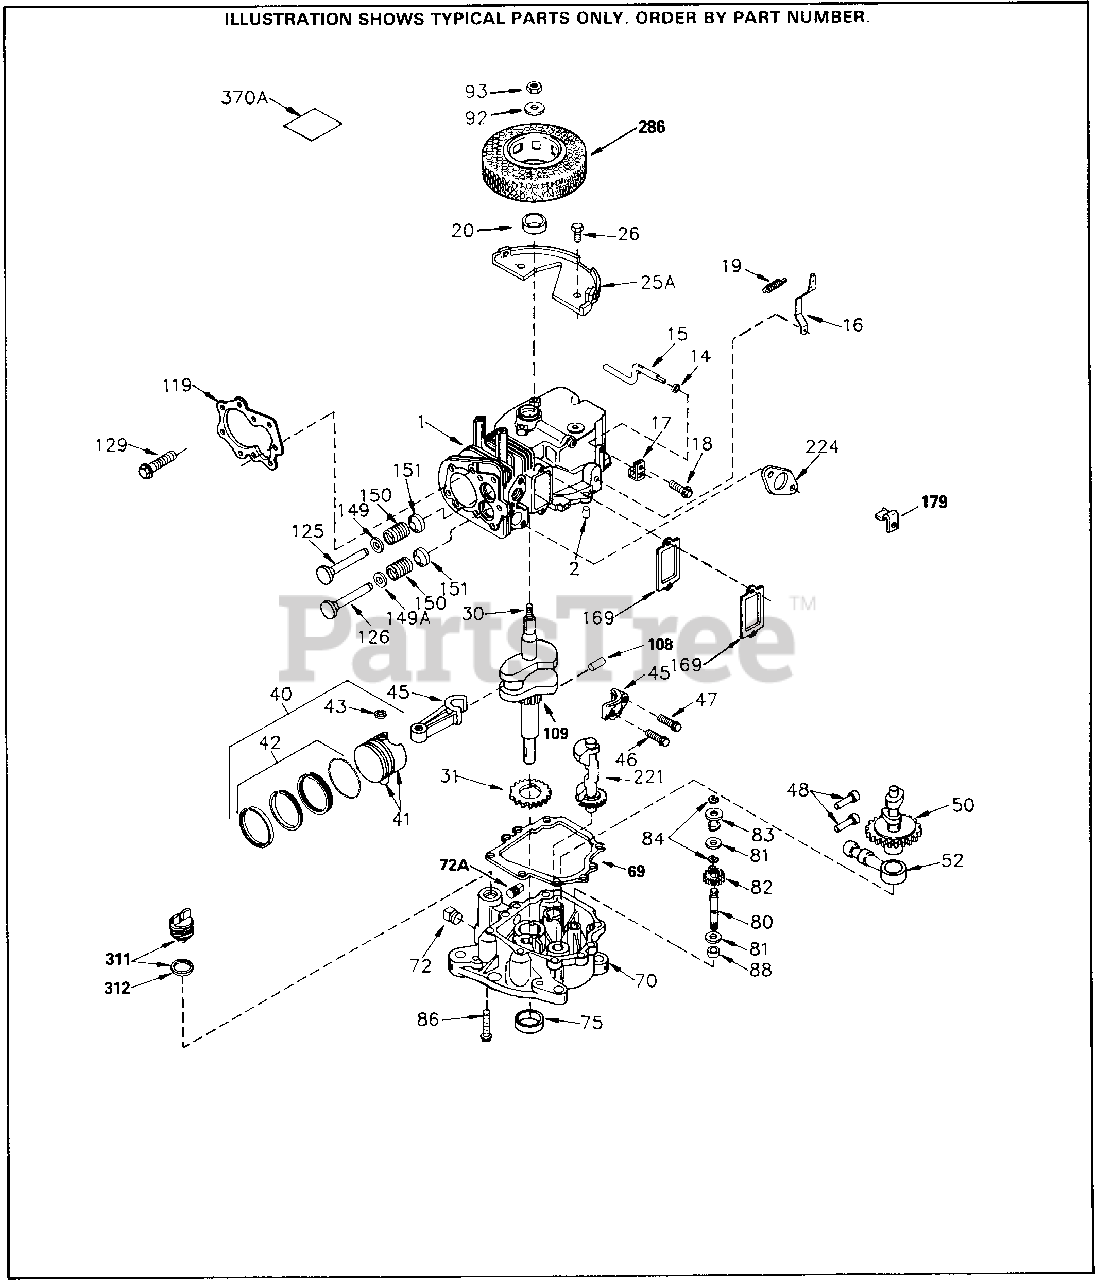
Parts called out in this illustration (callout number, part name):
1	"Cylinder (CI liner)(Incl. 2 & 20)
2	Dowel Pin
14	Flat Washer
15	Governor Rod
16	Governor Lever
17	Governor Lever Clamp
18	Screw, Torx T-15, 8-32 x 19/64"
19	Extension Spring
20	Oil Seal
30	Crankshaft
31	Counterbalance Gear
40	Piston, Pin & Ring Set (Std.) 3-1/8"B ore
40	Piston, Pin & Ring Set (.010" OS)
40	Piston, Pin & Ring Set (.020" OS)
41	Piston & Pin Ass'y. (Std.)(Incl. 43) 3-1/8"
41	Piston & Pin Ass'y. (.010" OS) Incl. 43
41	Piston & Pin Ass'y. (.020" OS) Incl. 43
42	Ring Set (Std.) (3-1/8" Bore)
42	Ring Set (.010" OS)
42	Ring Set (.020" OS)
43	Piston Pin Retaining Ring
45	Connecting Rod Ass'y. (Incl. 47)
47	Connecting Rod Bolt
48	Valve Lifter
50	Camshaft (MCR)
51	Couterbalance Weight
52	Oil Pump Ass'y.
69	Mounting Flange Gasket
70	Mounting Flange (Incl. 72, 72A, 75 & 80) 80)
72	Oil Drain Plug (3/8-18 Sq. hd.)
72A	Oil Drain Plug (3/8-18)
75	Oil Seal
80	Governor Shaft
81	Flat Washer
82	Governor Gear Ass'y. (Incl. 81)
83	Governor Spool
84	Retaining Ring
86	Screw, 1/4-20 x 1-3/16"
88	Governor Gear Spacer (Incl. 81)
125	Exhaust Valve (Std.)(Incl. 151)
125	Exhaust Valve (1/32" OS) (Incl. 151)
126	Intake Valve (Std.) (Incl. 151)
126	Intake Valve (1/32" OS) (Incl. 151)
149	Valve Spring Cap
149A	Intake Valve Seal Assy.
150	Valve Spring
151	Lower Valve Spring Cap
169	Valve Cover Gasket
224	Intake Pipe Gasket
311	Oil Fill Plug (Incl. 312) also availa ble in Packaged Part #740079
370A	Identification Decal
370G	Lubrication Decal
